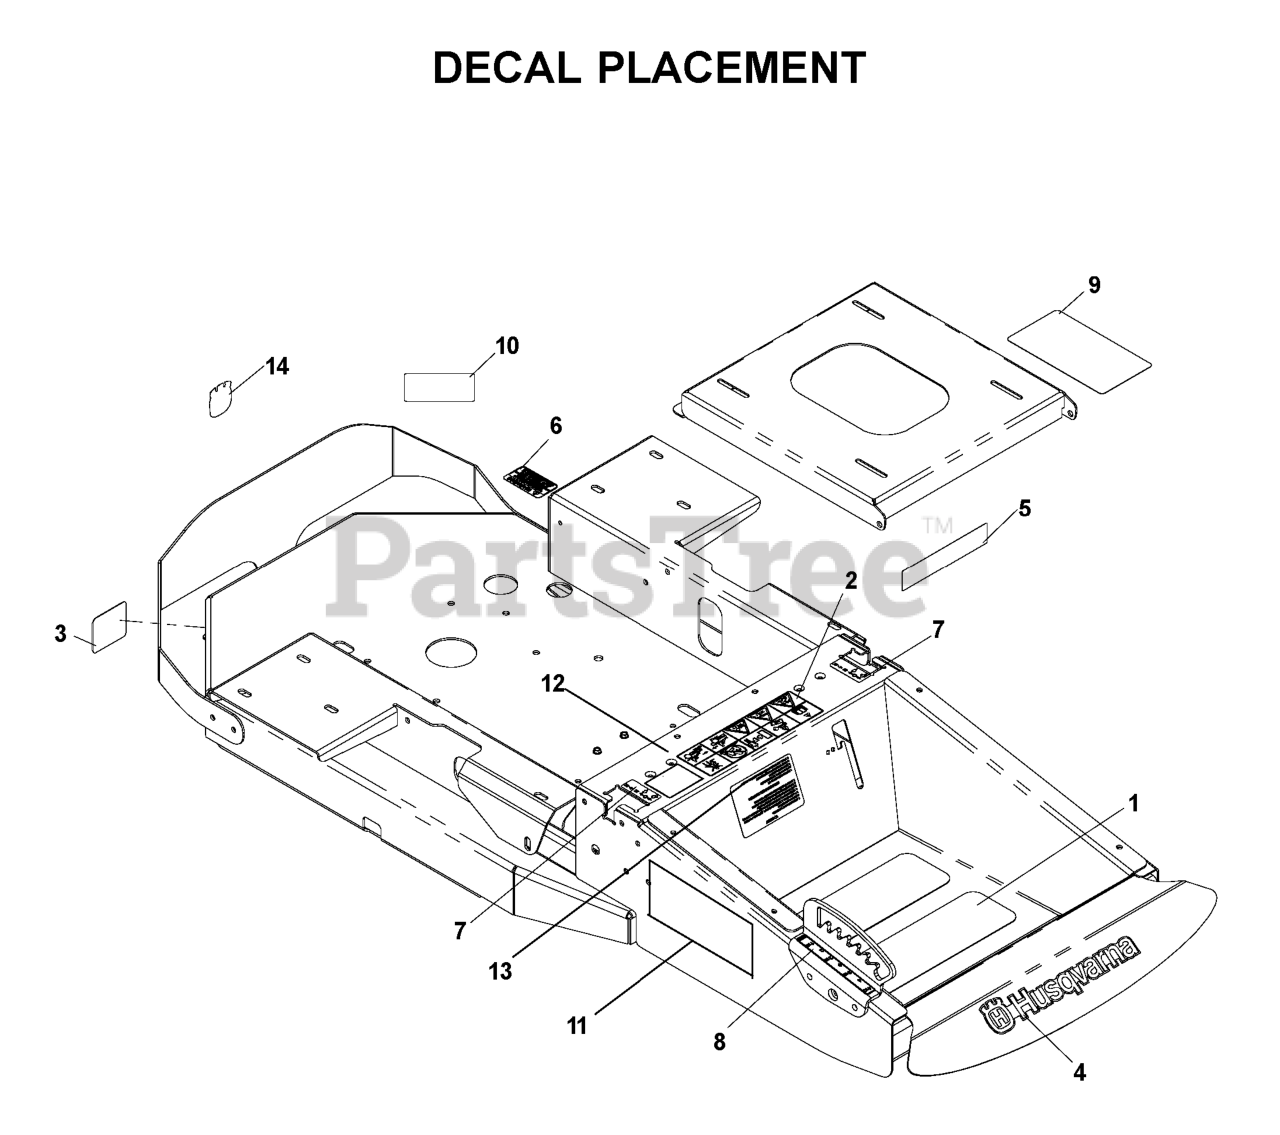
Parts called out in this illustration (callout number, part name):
1	ANTI-SKID PAD
2	DECAL, WARNING
3	DECAL, DO NOT TOW
4	DECAL, HUSQ 12" BLUE
5	EURO DECAL-BATTERY WARNIN6
6	DECAL, PROP. 65
7	DECAL, MOTION CONTROL
8	DECAL, CUTTING HEIGHT
9	DECAL-SERVICE
10	DECAL, BELT DRIVE
11	DECAL, CZ4815
12	DECAL, EXITING MOWER
13	DECAL, START
539107889	DECAL, CZ4817
